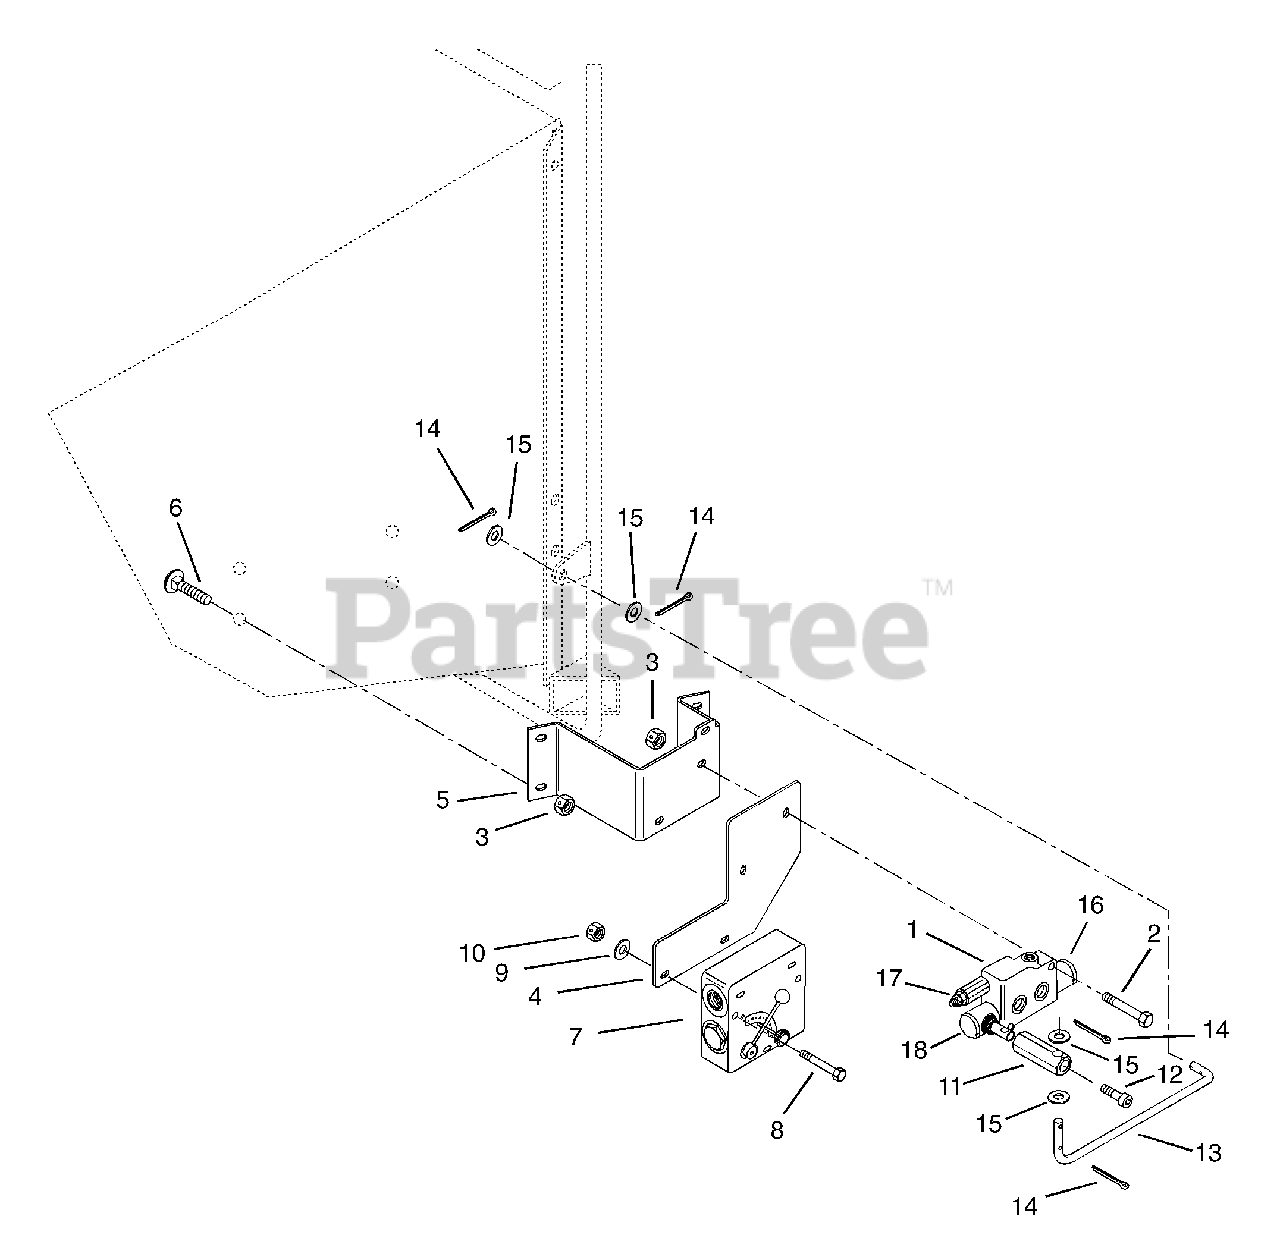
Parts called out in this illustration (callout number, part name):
1	Valve-Hydraulic
2	Bolt-Hex .31-18 x 2.50 Grade 5
3	Nut-Locking-Center .31-18
4	Bracket-Manual Feed
5	Bracket-Valve Mount
6	Bolt-Round Head Square Neck .31-18 x 1.00 Grade 5
7	Valve-Hydraulic Flow Control
8	Bolt-Hex .25-20 x 2.50 Grade 5
9	Washer-Flat-Steel .312 x .734 x .065
10	Nut-Locking-Center .25-20
11	Adapter-Hex
12	Screw-Socket Head M8 x 1.25 x 20 mm
13	Rod-Control Valve
14	Pin-Cotter .12 x .75
15	Washer-Flat-Steel .406 x .812 x .065
16	Detent Assembly-Control Valve
17	Relief Valve-Hydraulic Control Assembly
18	Lever Assembly-Hydraulic Control Valve
